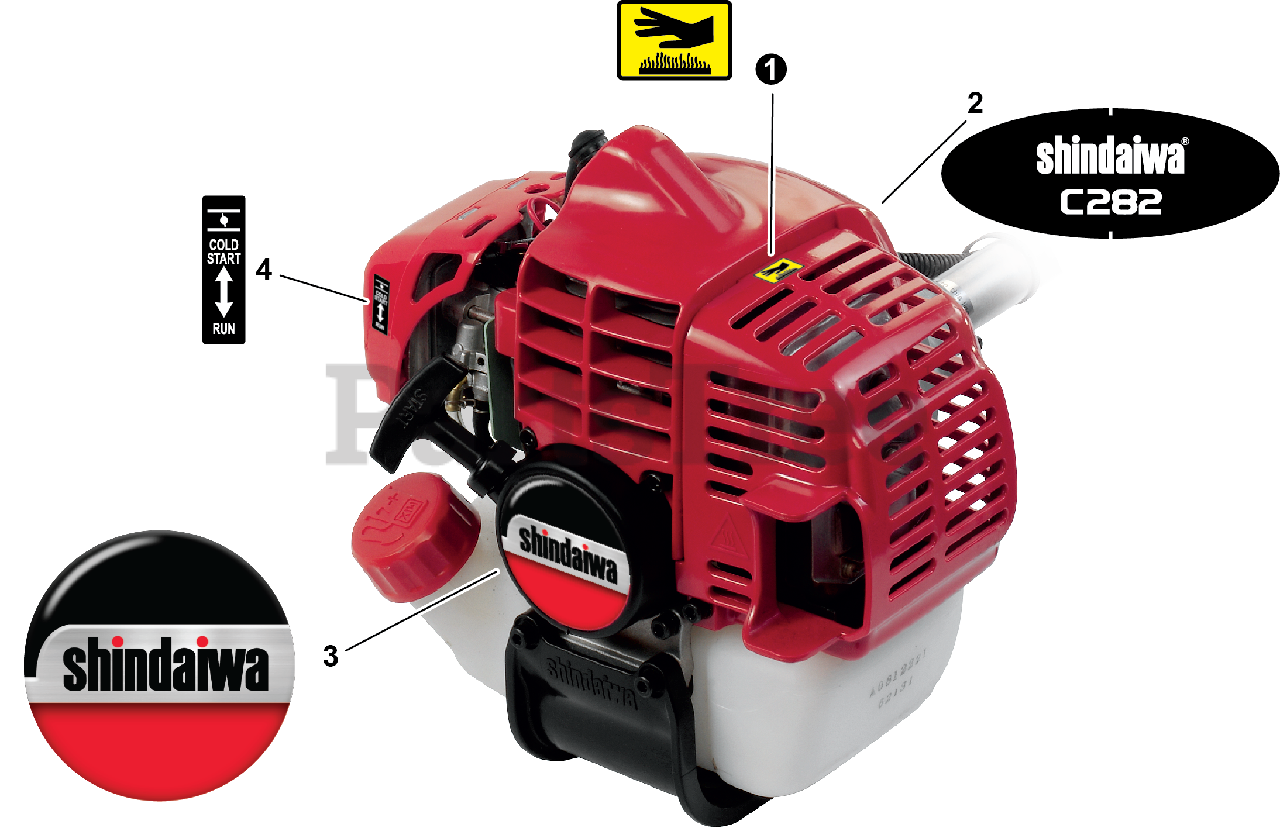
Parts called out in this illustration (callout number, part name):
1	LABEL, CAUTION - HOT
2	LABEL - MODEL C282
3	LABEL, RECOIL STARTER
4	LABEL, CHOKE
